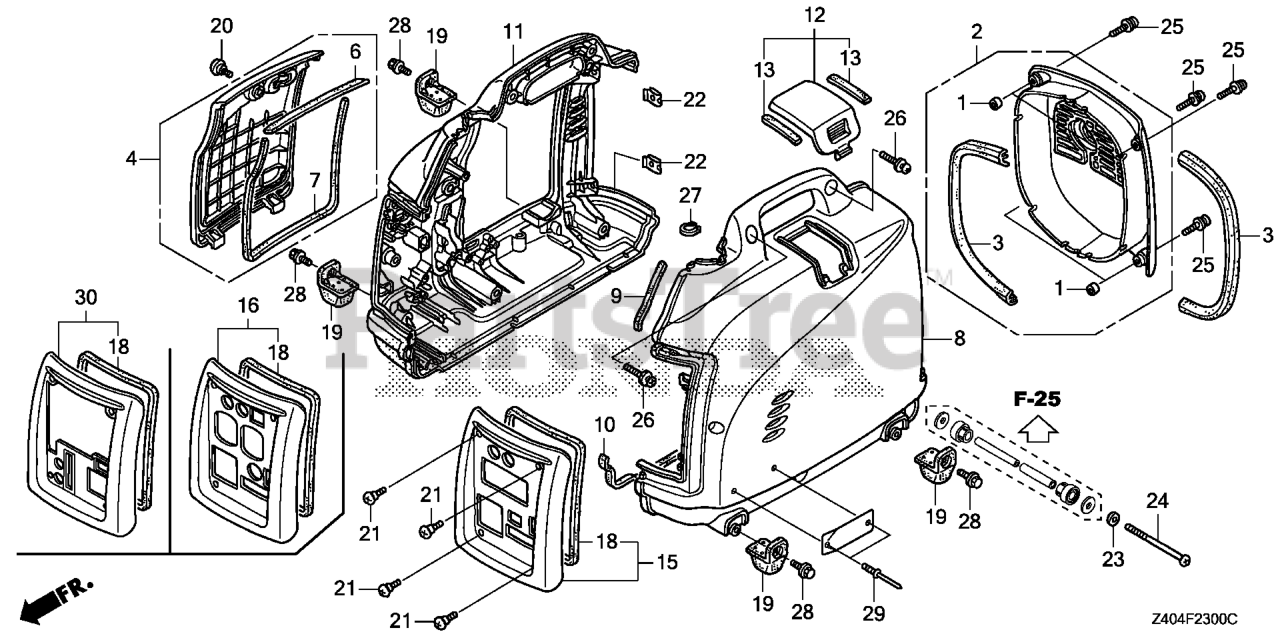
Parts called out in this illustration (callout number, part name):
1	COLLAR, CONTROL COVER
2	PROTECTOR, MUFFLER
3	SEAL RUBBER, PROTECTOR
4	COVER ASSY., MAINTENANCE
6	SEAL A, MAINTENANCE COVER
7	SEAL B, MAINTENANCE COVER
8	COVER, R. SIDE
9	SEAL A, SIDE COVER
10	SEAL B, SIDE COVER
11	COVER, L. SIDE
12	COVER ASSY., PLUG CHECK
13	SEAL, PLUG CHECK
18	SEAL, FR. COVER
19	RUBBER (LOWER)
20	SCREW, SPECIAL (6X16)
21	SCREW, FR. COVER
22	NUT, SPRING (5MM)
23	WASHER (6MM)
24	SCREW, PAN (6X100)
25	SCREW-WASHER (5X16)
26	SCREW-WASHER (6X20)
27	CIRCLIP (OUTER) (10MM)
28	BOLT, FLANGE (6X10)
30	COVER ASSY., FR.
